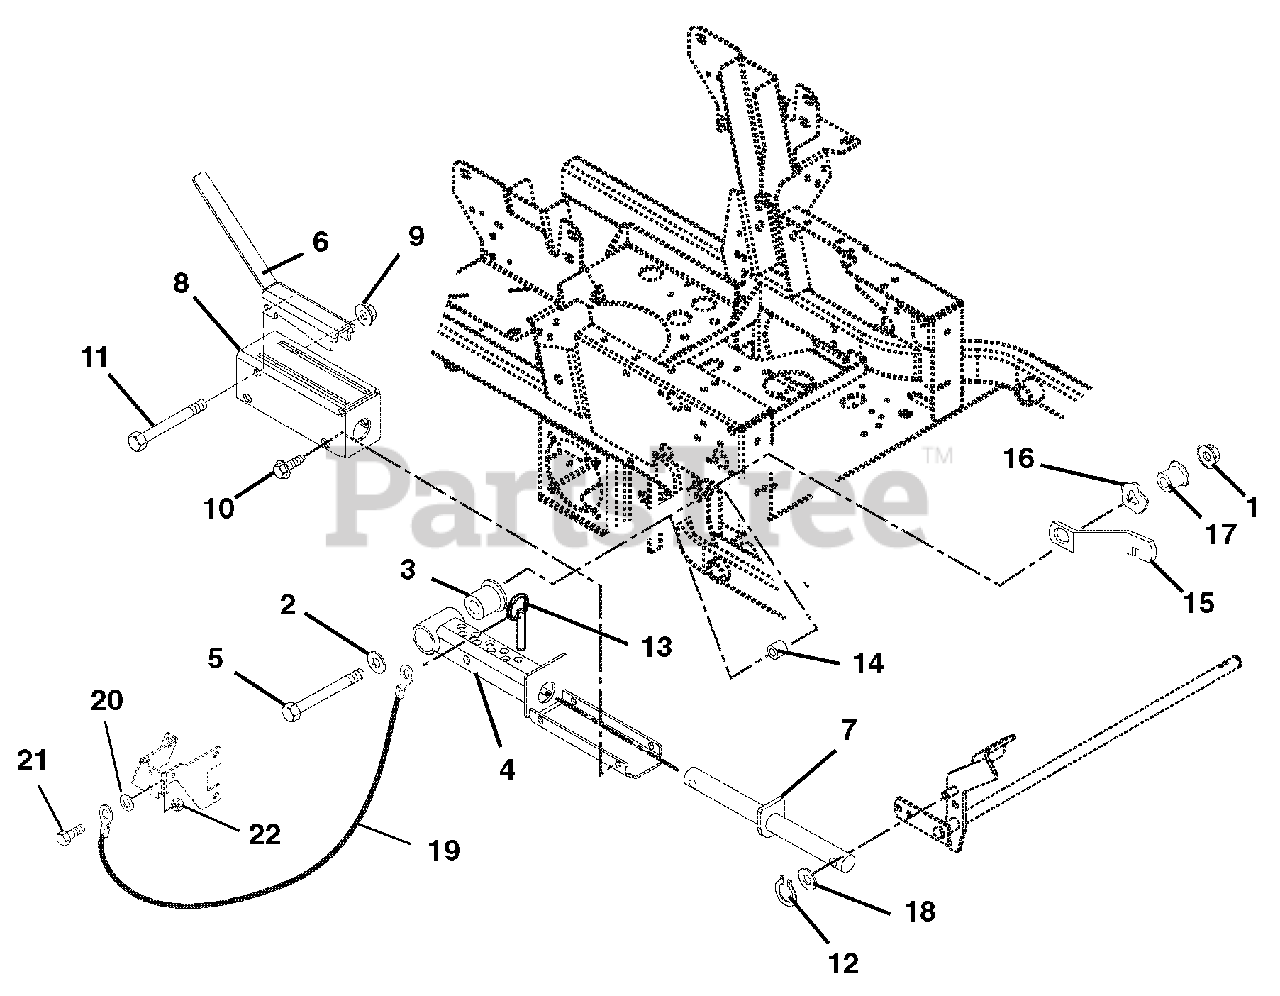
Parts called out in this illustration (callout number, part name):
1	Nut, Locking Top Flange .50-13
2	Washer, Flat Steel .531 x 1.25 x .10
3	Bearing, Pedestal
4	Weldment, Mechanical Lift
5	Bolt, Hex .50-13 x 5.00 Grade 5
6	Lock-Up, Mechanical Lift
7	Weldment, Mechanical Lift Shaft
8	Weldment, Mechanical Lift Cover
9	Nut, Locking Top Flange .38-16
10	Screw, Tapping .38-16 x .50 Hex Washer Head
11	Bolt, Hex .38-16 x 3.25 Grade 5
12	Ring, Retaining External .625 x .05
13	Pin, Spring Ball .375 O.D. x 1.50
14	Spacer .516 I.D. x 1.00 O.D. x .875
16	Washer, Wave .076 x 1.120 x .080
17	Bushing, Flange .515 x .750 x .275 x 1.120
18	Washer, Flat Steel .656 x 1.31 x .095
19	Cable, Hood
20	Washer, Flat Steel .265 x .50 x .087
21	Bolt, Hex .25-20 x .75 Grade 5
22	Nut, Locking Top Flange .25-20
